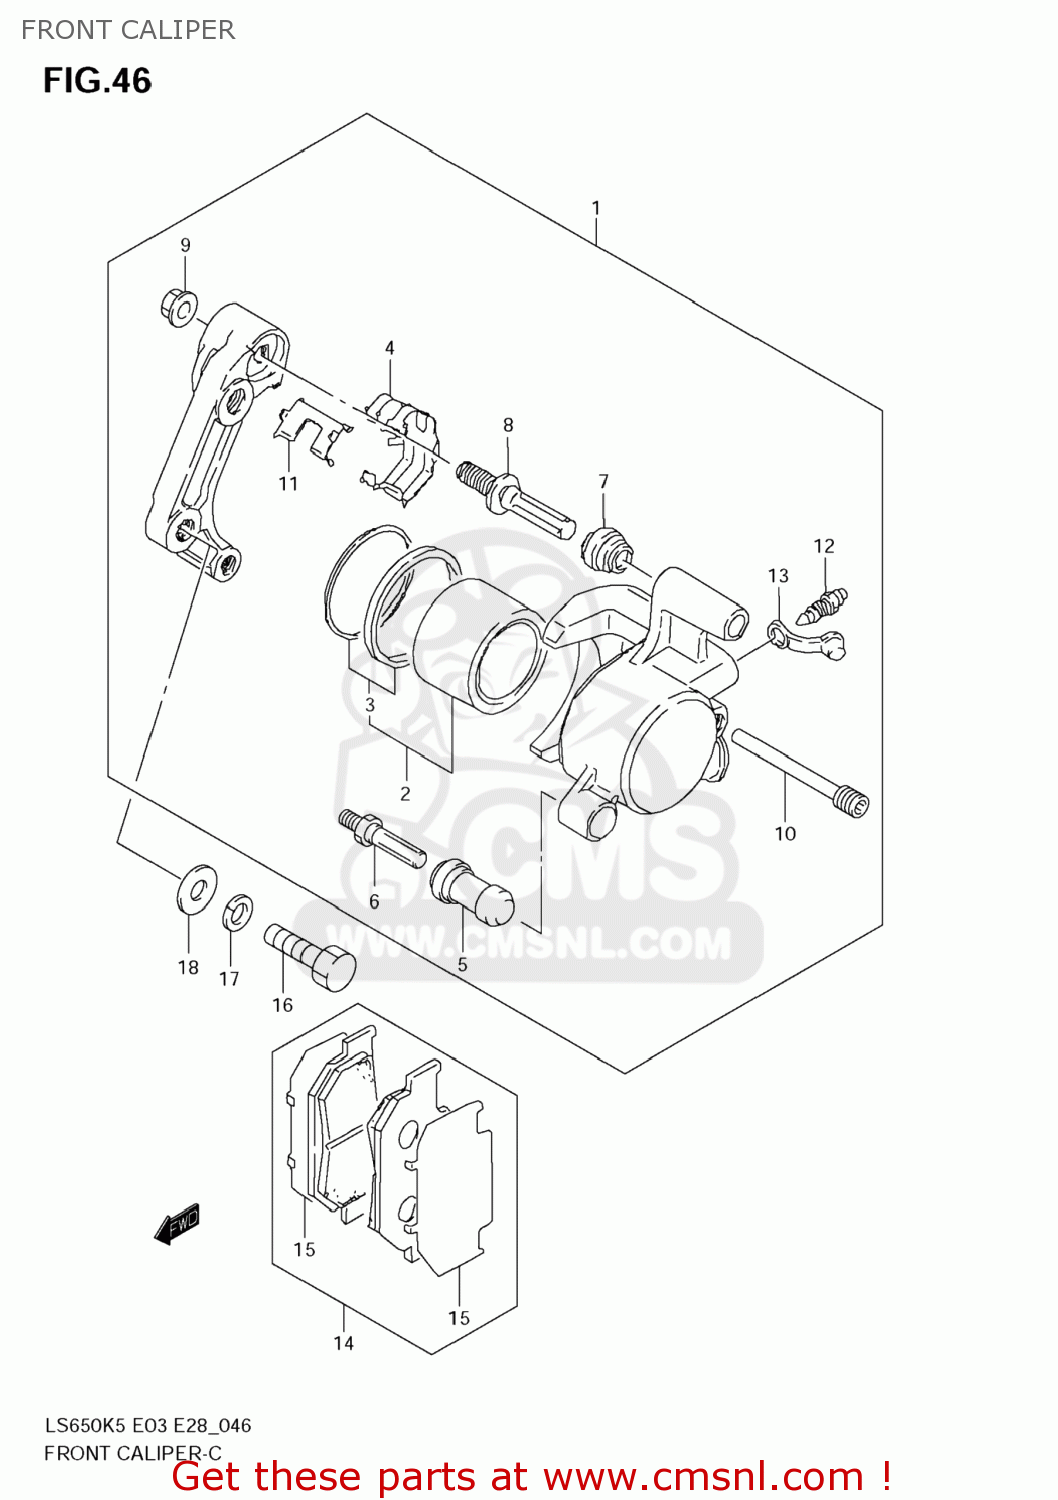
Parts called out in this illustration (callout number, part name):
1	CALIPER ASSY,FR
2	PISTON SET
3	SEAL SET,PISTON
4	SPRING
5	BOOT
6	BOLT
7	BOOT
8	PIN,SLIDE
9	NUT,SLIDE PIN
10	PIN,HANGER
11	RETAINER
12	BLEEDER
13	CAP,BLEEDER
14	PAD & SHIM SET (NAS)
15	SHIM
16	BOLT(10X38)
17	WASHER,LOCK
18	WASHER
